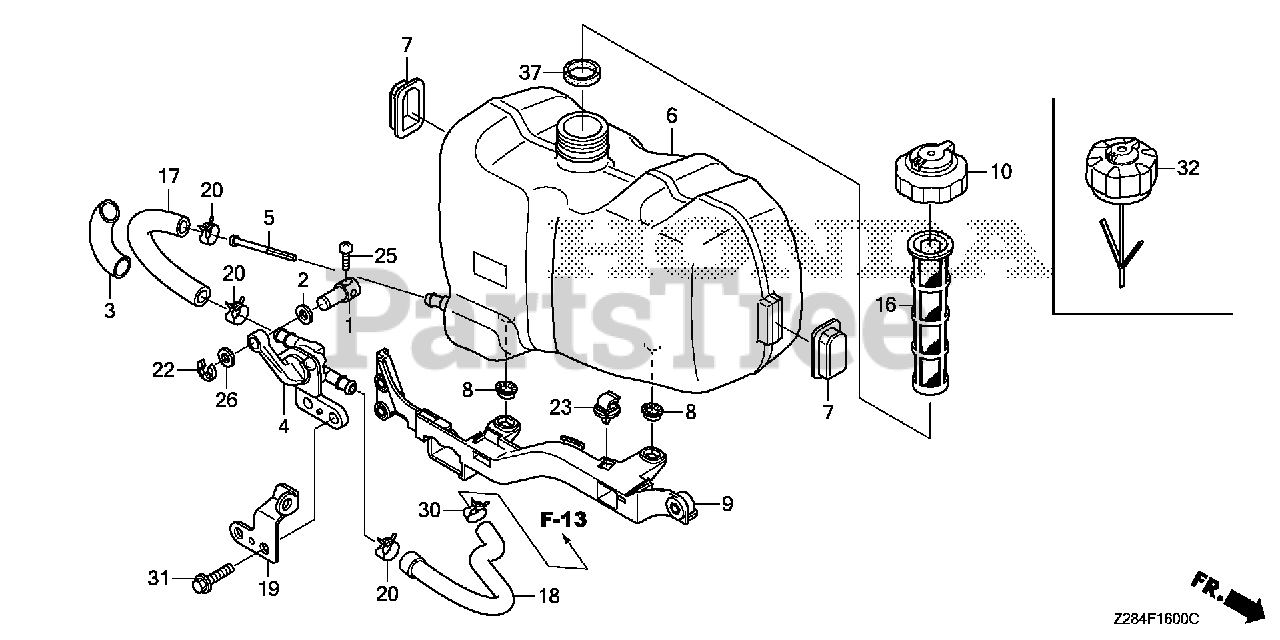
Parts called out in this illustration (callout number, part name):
1	HOLDER, CABLE
2	WASHER, CABLE HOLDER
3	RUBBER, SUPPORTER
4	PETCOCK ASSY.
5	FILTER, FUEL
6	TANK, FUEL (COO)
7	RUBBER A, TANK MOUNTING
8	RUBBER B, TANK MOUNTING
9	BRACKET, FUEL TANK
10	CAP ASSY., FUEL TANK
11	INNER, FUEL CAP (NOT AVAILABLE)
12	SPONGE, FUEL CAP BREATHER
13	GASKET, FUEL CAP
14	VALVE, BREATHER
15	SPRING, FUEL CAP
16	FILTER, FUEL
17	TUBE, FUEL TANK (FKM)
18	TUBE, FUEL PETCOCK (FKM)
19	HOLDER, PETCOCK CABLE
20	CLAMP, MASTER CYLINDER OIL HOSE
21	WASHER (6MM)
22	CIRCLIP (5MM)
23	CLAMP, WIRE (8MM)
24	O-RING (13.8X2.4) (N/A: SEE ASSEMBLY)
25	SCREW, PAN (4X6)
26	WASHER, PLAIN (6MM)
27	PIN, LOCK (6MM)
30	CLAMP, TUBE (D10)
31	BOLT, FLANGE (6X16)
37	RUBBER C, TANK MOUNTING
